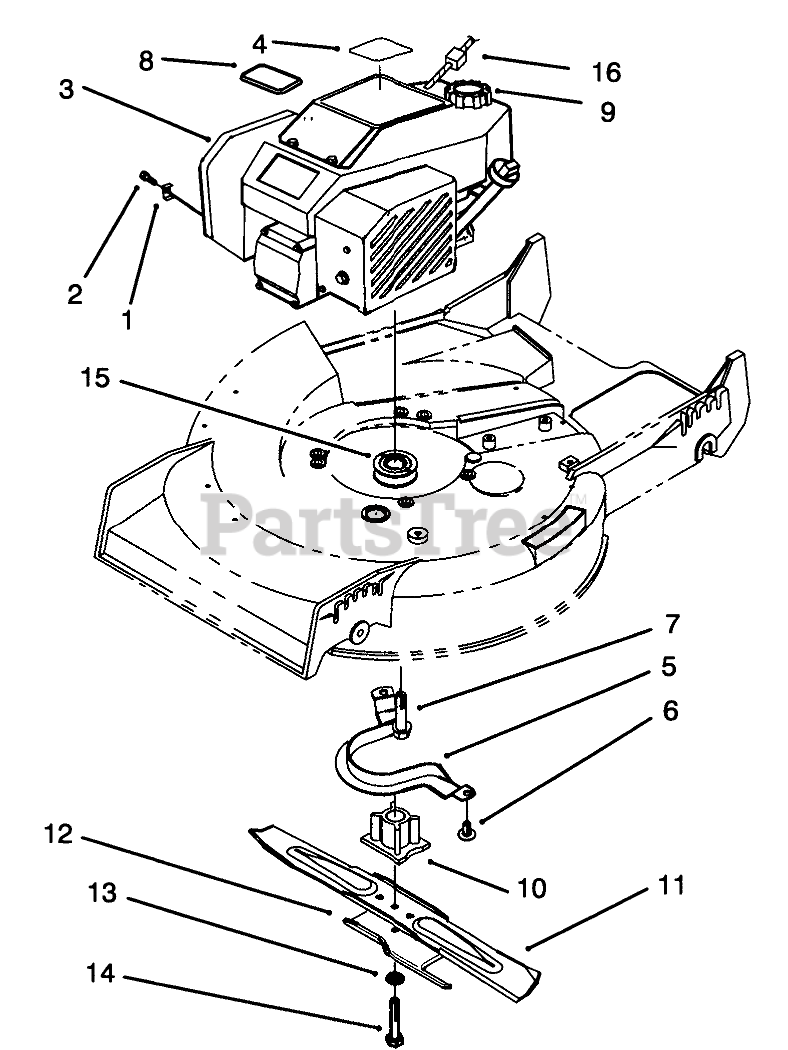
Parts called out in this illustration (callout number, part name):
1	CLAMP-CASING
2	CLAMP SCREW F/W ENGINE
3	Engine (Incl. Ref. #4, 8, & 9)
4	DECAL - ENGINE
5	Guide-Belt
6	SCREW-HWHTF
7	SCREW-HWH
8	PLATE-LOGO
9	ASSY FUEL CAP
10	BLADE RETAINER
11	Blade
12	Accelerator
13	WASHER-LOCK
14	SCREW-BLADE
15	PULLEY-DRIVE, ZONE START
16	STOP-ROPE
